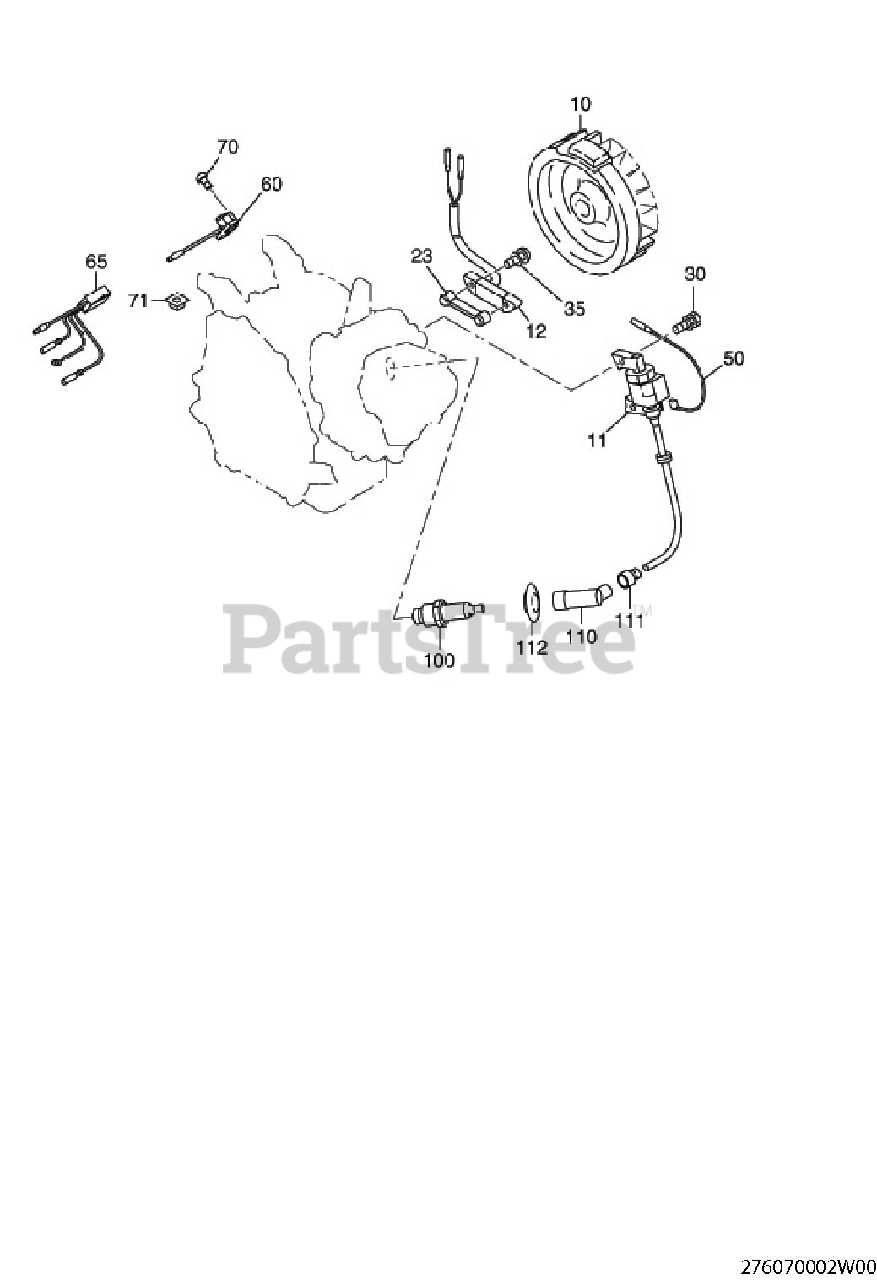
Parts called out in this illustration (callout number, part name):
11	IGNITION COIL CP
30	BOLT AND WASHER AY
50	WIRE 2 CP
70	TAPPING SCREW
100	SPARK PLUG
110	SPARK PLUG CAP
